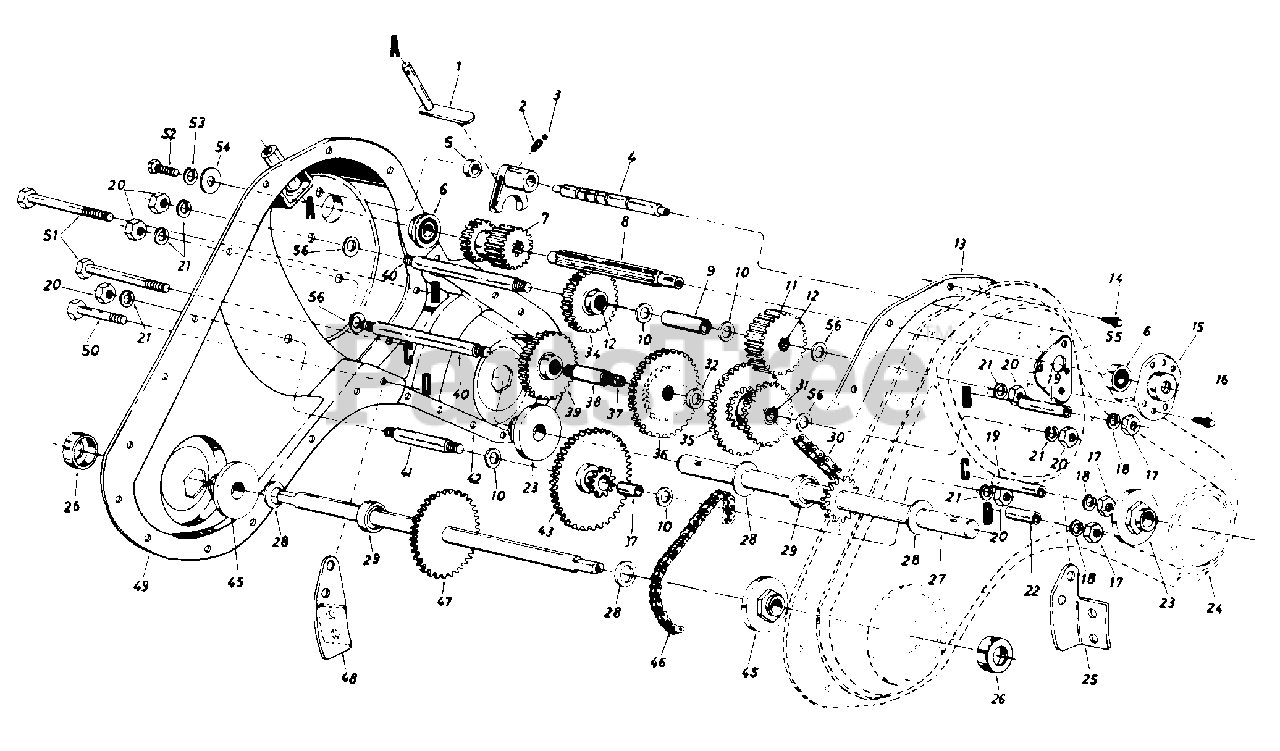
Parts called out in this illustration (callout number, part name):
1	Shifting Bracket Ass'y.
2	Compression Spring .50" Lg.
3	Ball Detent .250" Dia.
4	Detent Shaft 1/2" Dia.
5	Spacer .505" I.D. x .88" O.D.
6	Ball Brg. .62" I.D. x 1.38"
7	Spur Gear 16T
8	Input Spline Shaft 7/8
9	Spacer .657" I.D. x 718" O.D. x 2.85" Lg.
10	Fl-Wash. .640" I.D. x 1.24"
11	Spur Gear 30T 718" I.D. x 1-1/4" O.D.
12	Needle Bearing 518" I.D. x 718" O.D.
13	Gasket Trans. Hsg.
14	Hex Wash. S-Tap Scr. '/4-20 x.50" Lg.
15	1-3/8" Dia. Bearing Housing
16	Hex TT-Tap Scr. 1/4-20 x .75" Lg.
17	Hex Nut 5/16-18 Thd.
18	L-Wash. 5/16" I.D.
19	Spacer 1.56" Lg.
20	Hex Nut 7/16-20 Thd.
21	Bell-Wash. .45" I.D. x 1.0"
22	Spacer 1.015" Lg.
23	Tine Shaft Brg. 1.002 x 2.50
24	Trans. Housing Ass'y. L.H.
27	Tine Shaft Ass'y. 1.00" O.D.
28	Thrust Washer 1.030 I.D. x 1.62" O.D.
29	Spacer 1.0" I.D. x .50" Lg.
30	Chain #50 5/8 Pitch x 52 Links Endless
31	Needle Bearing 5/8" I.D.
32	Fl-Wash. 5/8" I.D. x 1-1/4" O.D. x .150
34	Spur Gear 30T 12/16" I.D. x 1/2" W
35	30/44T Gear Ass'y. Comp.
36	Spur Gear 44T
37	Sleeve Bearing
38	Gear Hub 3/4" I.D. x 3.0" Lg.
39	Spur Gear 30T 1.0" I.D. x 1/2" W
40	Jack Shaft 5/8" Dia. x 5.0"
41	Jack Shaft 5/8" Dia. x 2.38"
45	Wheel Brg. .752 x 2.50
46	#420 Chain 1/2 Pitch x 50 Links Endless
47	Wheel Shaft Ass'y. 15.6"
51	Hex Bolt 5/16-18 x 2.50
52	Hex Bolt 1/4-20 x .62" Lg.
53	L-Wash. 3/8" I.D.
54	Fl-Wash. 1/4" I.D. x .93" O.D.
55	Gear Positioner Bracket
56	Fl-Wash. 7/16" I.D. x 1-3/8" O.D.
